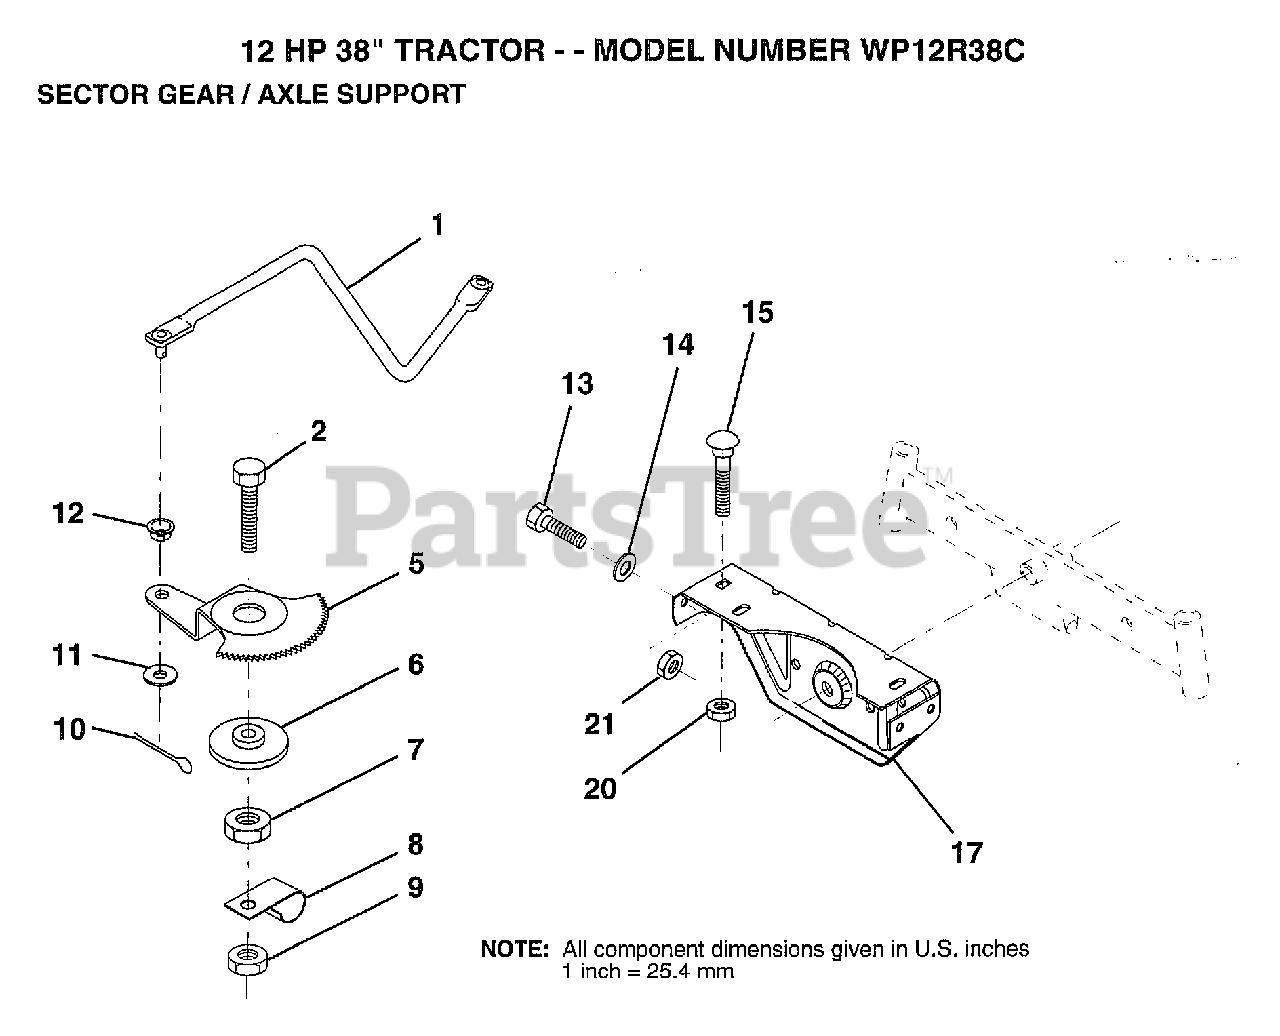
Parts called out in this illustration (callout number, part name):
1	DRAG LINK
2	"BOLT,HEX"
5	GEAR SECTOR
6	BUSHING
7	NUT
8	CLIP INSULATOR
9	NUT LTV
10	COTTER PIN
11	WASHER
12	BUSHING.DRAGLINK
13	BOLT
14	WASHER
15	BOLT
17	SUPT AXLE FRONT
20	NUT
21	NUT
